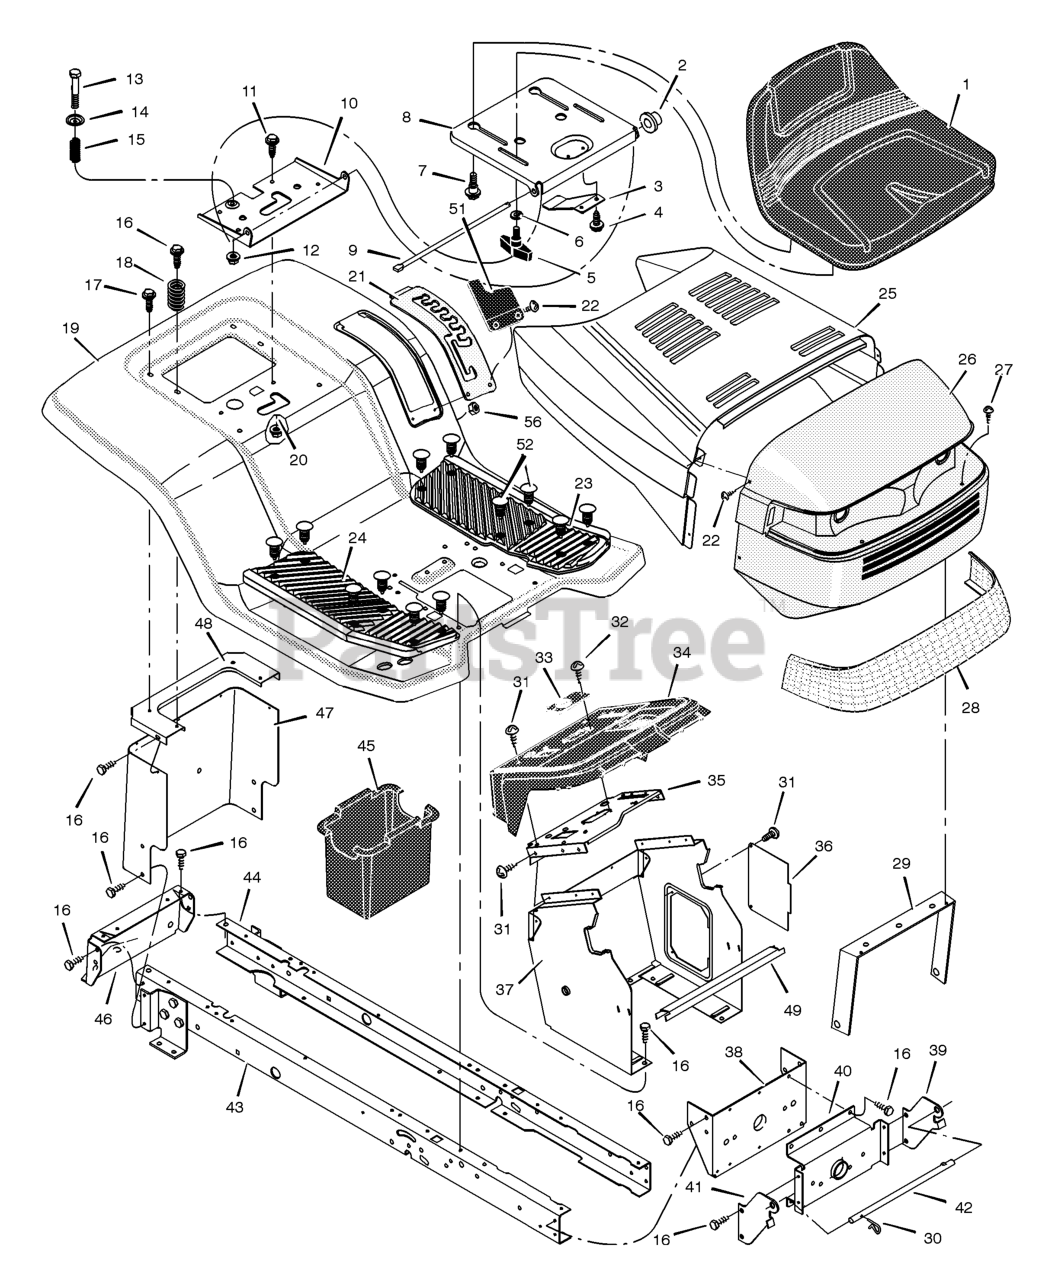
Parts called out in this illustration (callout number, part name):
1	Seat
2	Cap, Push On
5	Bolt, Wing
6	Washer
7	Bolt, Shoulder
8	Support, Seat
9	Rod, Pivot
10	Bracket, Pivot
11	Bolt
13	Bolt, Shoulder
15	Spring
19	Deck, Seat
20	Nut
21	Plate, Index
23	Mat, Left
24	Mat, Right
25	Hood
26	Grille Assembly
29	Brace, Grille
30	Pin, Hair
31	Screw
33	Bearing, Steering
35	Plate, Dash
36	Panel, Access
37	Support, Dash
38	Bracket, Rear Hanger
39	Support, Left Grille
40	Axle, Hanger
41	Support, Right Grille
42	Rod, Pivot
43	Frame, Right
44	Frame, Left
45	Container, Battery
46	Plate, Hitch
47	Plate, Rear
48	Top, Rear Plate
51	Cover, Detent
52	Fastener
56	Locknut
